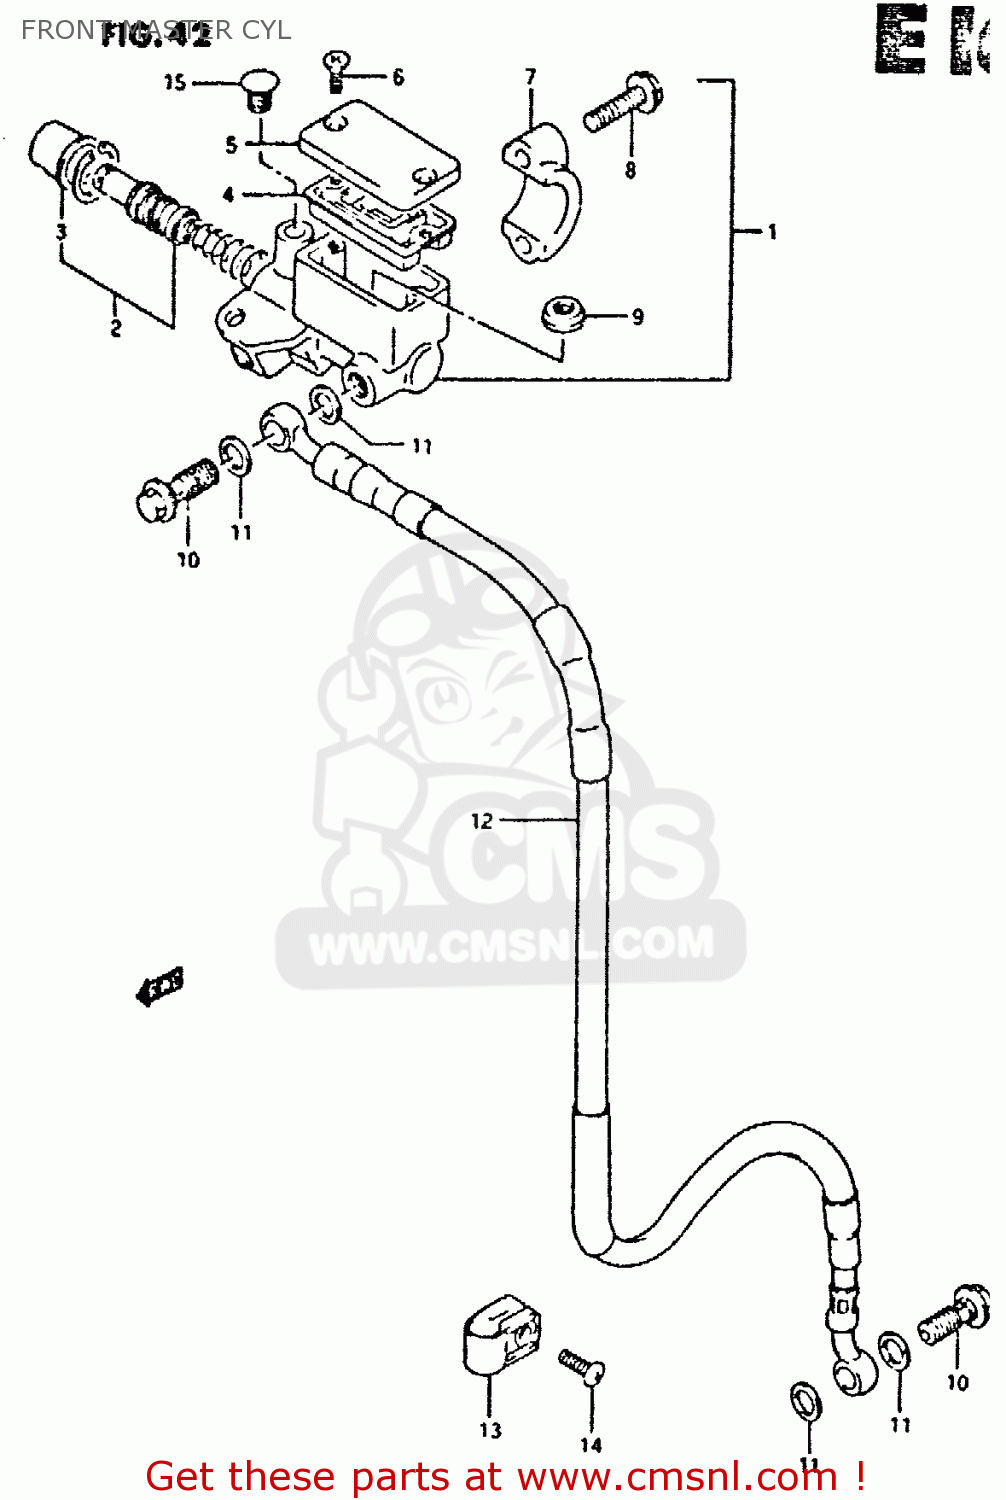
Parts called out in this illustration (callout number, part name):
1	CYLINDER ASSEMBLY,FRONT MASTER
2	PISTON & CUT SET
3	BOOT
4	DIAPHRAGM
5	CAP
6	SCREW
7	HOLDER
8	BOLT
9	SEPARATOR
10	BOLT UNION
11	WASHER(10X15X1.5)
12	HOSE,FR BRAKE
13	CLAMP,FR BRAKE HOSE
14	SCREW
15	CAP(OD:14)
